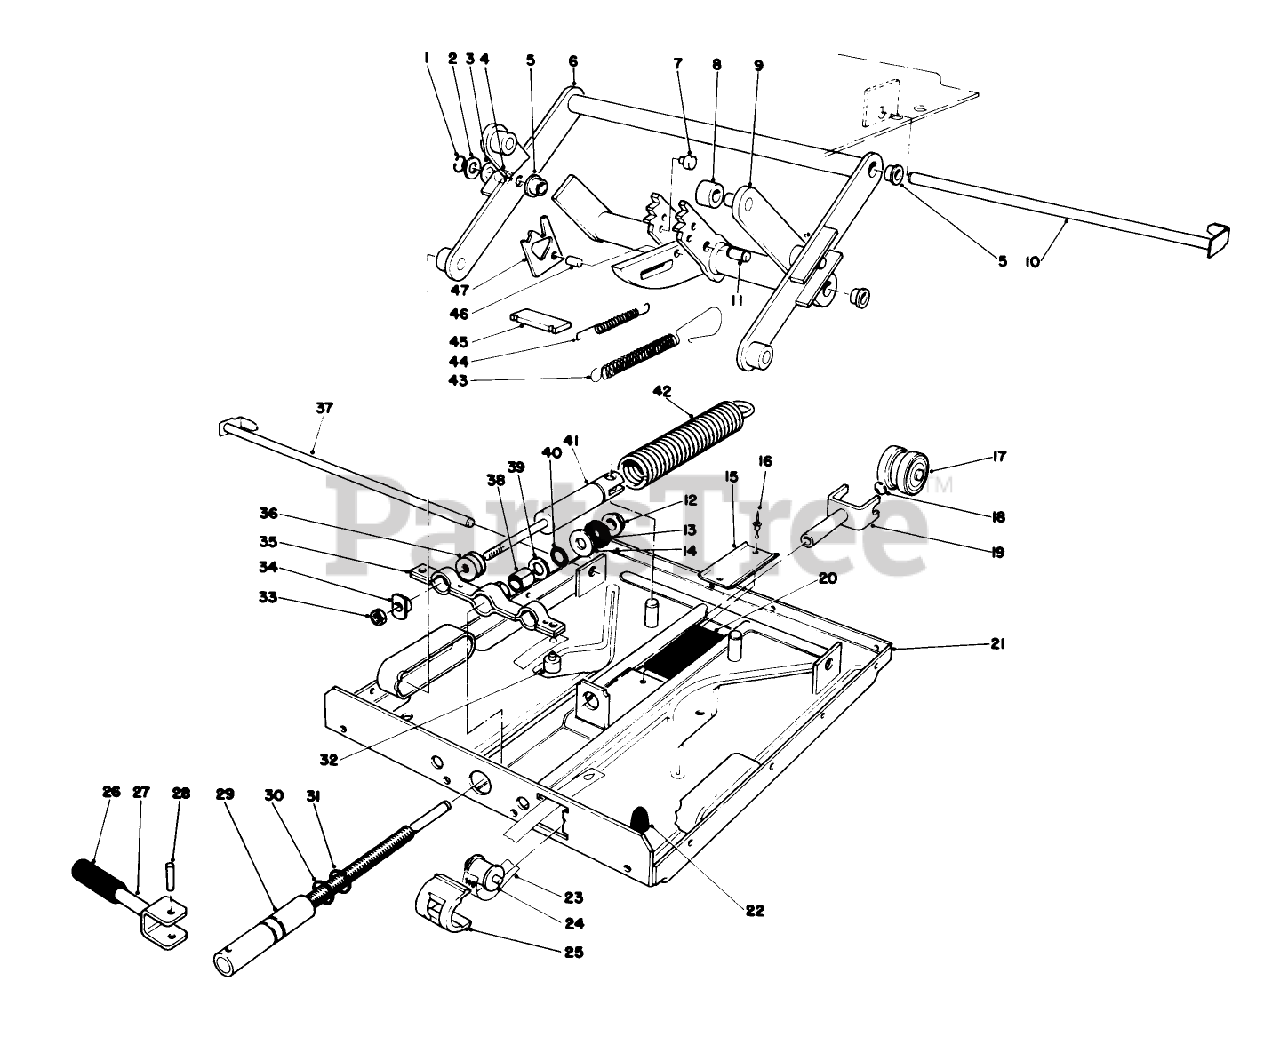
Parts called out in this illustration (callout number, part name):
1	WASHER
2	WASHER
3	WASHER
4	BRG BSHG
5	BEARING
6	Swing Arm-Outside
8	ROLLER
9	Frame Bag
11	Grooved Locking Pin 08X16CM
12	SLEEVE
13	WASHER-RUBBER
14	WASHER
15	U-TRACK
16	RIVET
17	TRIBLE BRG
18	RET RING
20	RUBBER
21	Lower Suspension Plate-Complete (Incl. Ref. #15-16 & 20)
22	BUMPER
23	WEIGHT INDICATOR BAND
24	ROLLER
25	GUIDE-SLEEVE
26	HANDLE
27	TOGGLE
28	GROOVED PIN
30	RUBBER RING 14MM BLK
31	RUBBER RING 14MM RED
34	WELD NUT
35	Spring Bracket
36	THREADED ROD
38	SLEEVE
39	WASHER
40	BEARING-THRUST, NEEDLE
41	SHOCK ABSORBER
42	COIL SPRING
43	SPRING-COIL
44	SPRING-COIL
45	PLATE
47	BRACKET-RELEASE
